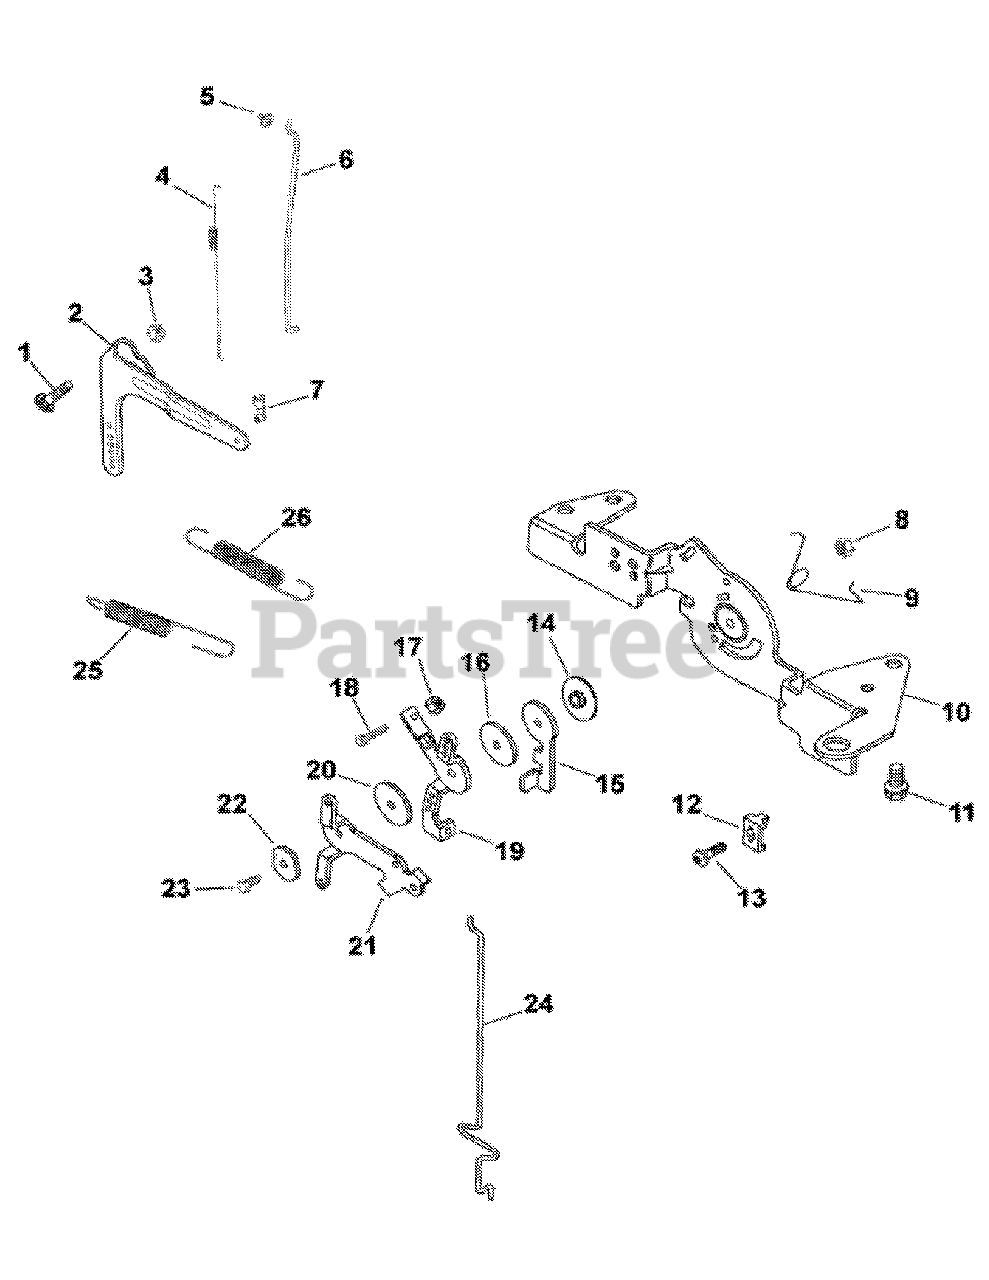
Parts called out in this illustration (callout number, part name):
2	Governor Lever
3	Hex Flange Nut
4	Linkage Spring
5	Linkage Retaining Bushing
6	Throttle Linkage
7	Throttle Linkage Bushing
9	Choke Return Spring
10	Control Bracket
11	Hex Flange Screw
12	Cable Clamp
13	Phillips Screw
15	Throttle Actuator Lever
18	Hex Cap Screw
19	Throttle Control Lever
20	Plain Washer
24	Choke Linkage
25	Governor Spring
26	Governor Spring
